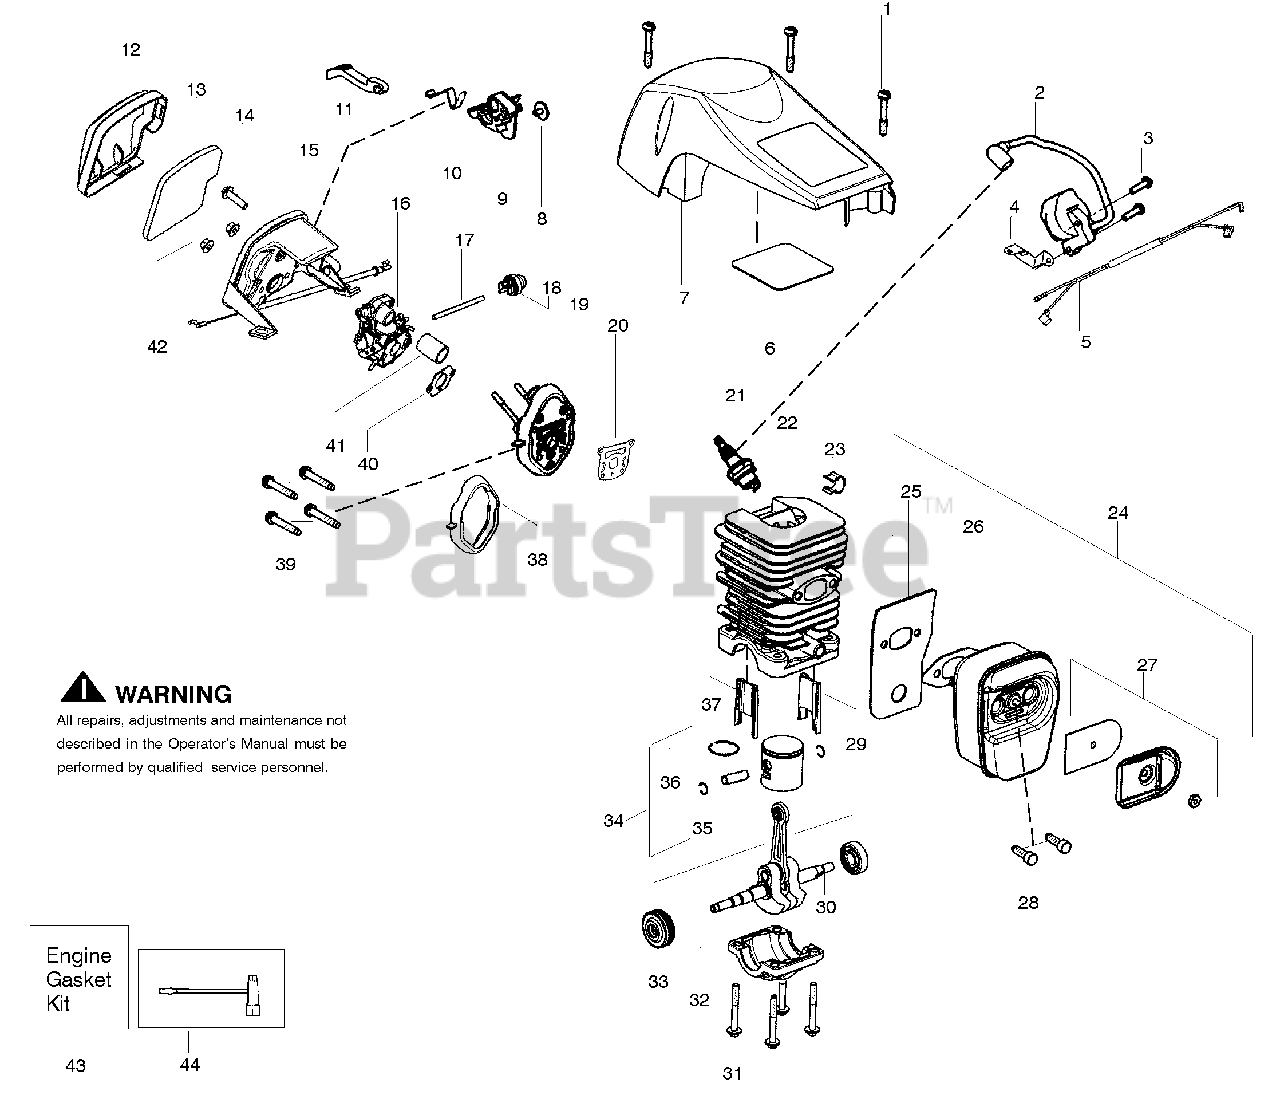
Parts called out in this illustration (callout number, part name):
2	Module-Ignition
5	Assy-Wire Harness
6	Reflector-Tape
7	Shield-Cylinder
9	Lever-Ignition Switch
10	Spring-Ignition Switch
12	Cover-Air Filter
15	Housing-Air Filter w/cable
16	Carburetor Zama W26B
17	Kit-Fuel Line (Small)
18	Bulb-Purge "snap-in"
19	Kit-Carb. Adaptor
20	Gasket-cyl. o-ring (kit)
21	Accy-Spark Plug (RCJ-7Y)
22	Kit-Cylinder
23	Clip-High Tension Lead
24	Kit-Muffler
25	Backplate-Muffler
26	Gasket-Muffler (kit)
27	Kit-Spark Arrestor
29	Insert-Left (black) Cyl.
30	Assy-Crankshaft/Rod
32	Cap-Crankcase
33	Assy-Bearing/Seal
34	Kit-Piston
35	Retainer-Piston Pin
37	Insert-Right (gray)Cyl.
38	Seal-Adaptor (kit)
40	Gasket-Carb. (kit)
43	Kit-Gasket
44	Scrench
